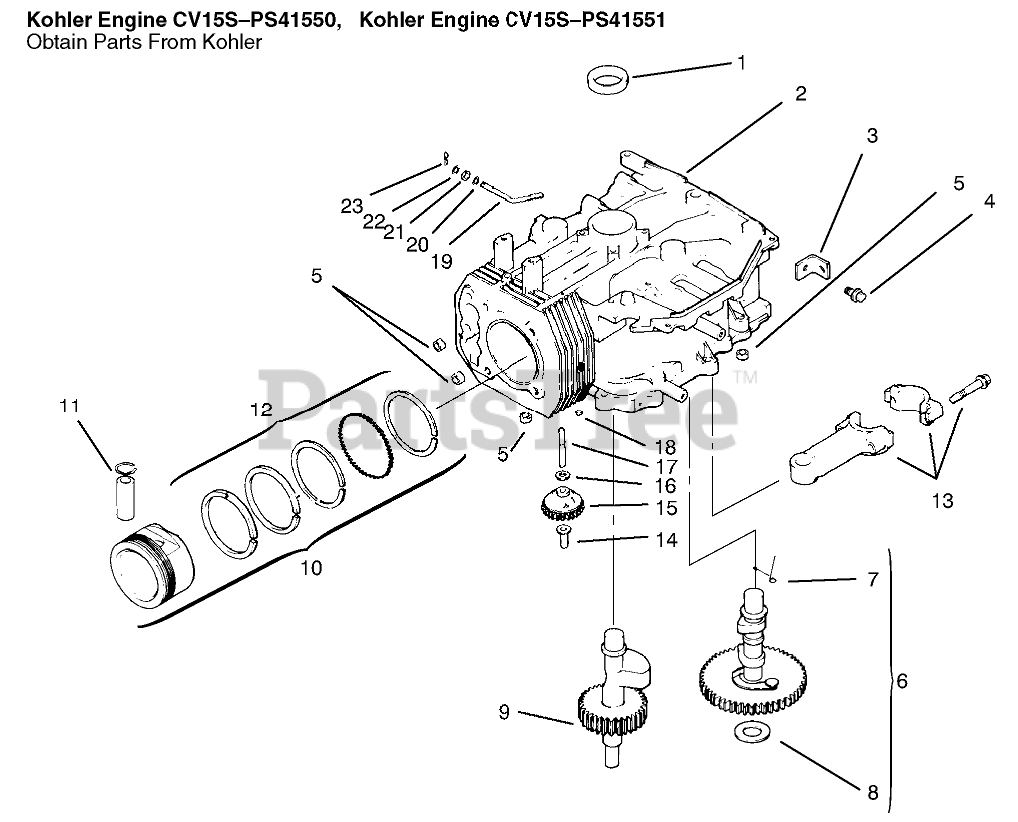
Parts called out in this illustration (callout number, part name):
1	Seal-Crankshaft
2	Block-Short
3	Strap-Lifting
4	Screw
5	Pin-Dowel
6	Camshaft Assembly
7	Spring-Actuating
8	Shim-Camshaft
9	Shaft-Balance
10	Piston ASM STD Incl 11-2
10	Piston ASM .25 Incl 11-2
10	Piston ASM .50 Incl 11-2
11	Retainer-Piston Pin
12	Ring Set STD
12	Ring Set .25
12	Ring Set .50
13	Rod Connecting STD
13	Rod Connecting .25
14	Pin-Governor
15	Gear, governor
16	Washer
17	Shaft-Gear, Governor
18	Plug
19	Kit-Governor Cross
20	Washer, plain 6 mm
21	Seal-Cross Shaft
22	Washer
23	Clip-Hitch Pin
